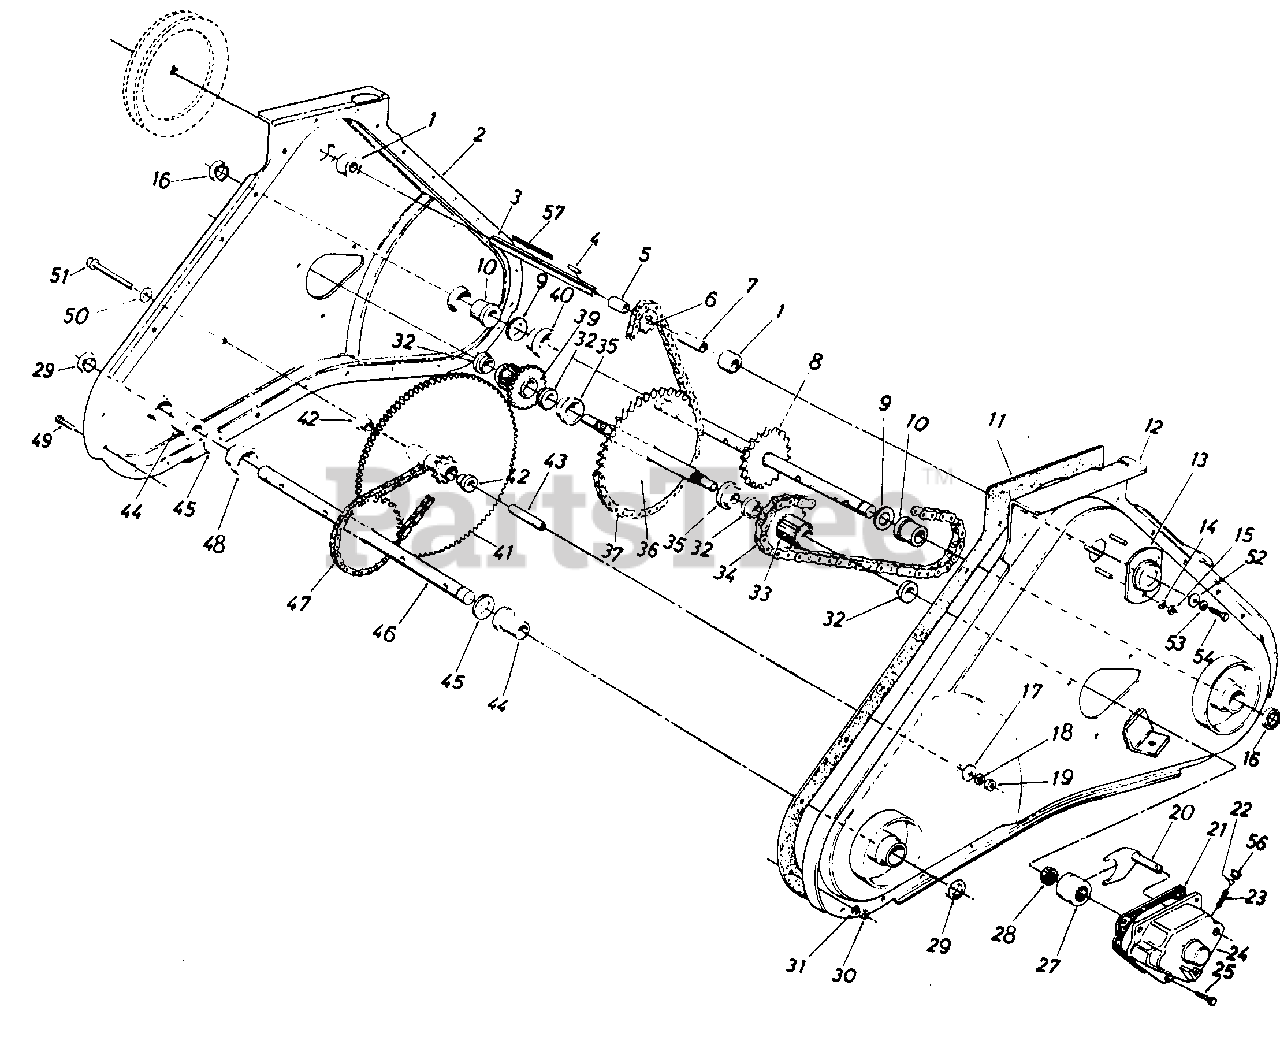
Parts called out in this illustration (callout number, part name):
1	Ball Bearing .62" I.D. x 1.38" O.D. x .44
2	Chain Case R.H. Half
3	Input Shaft .62" Dia.
4	Sq. Key 3/16" x 3/16" x .75" Lg.
5	Spacer .637" I.D. x .781" O.D. x.85" Lg.
6	Sprocket 9 Tooth x .62" Shaft
7	Spacer.637" I.D. x .781" O.D. x 1.44" Lg.
8	Tine Shaft Ass'y.
9	Fl-Wash. 1.28" I.D. x 1.62" O.D.
10	Flange Bearing 1.25" I.D.
11	Gasket Housing
12	Chain Case L.H. Half
13	Bearing Housing 1-3/8" O.D.
14	L-Wash. 1/4" I.D.*
15	Hex Nut 1/4-28 Thd.
16	Seal 1.25" I.D.
17	Belleville Wash.
18	L-Wash. 3/8" I.D.*
19	Hex Cent. L-Nut 3/8-24 Thd.
20	Shift Yoke Ass'y. L.H.
20	Shift Yoke Ass'y. R.H.
21	Gasket Shift Housing
22	Ball Detent .250 Dia.
23	Compression Spring
24	Shift Housing L.H.
24	Shift Housing R.H.
25	Hex Tap-Tite 5/16-18 x .75" Lg.
27	Clutch Dog
28	Clutch Dog Driver
29	Seal 1.0" I.D. x 1.38" O.D.
30	Hex Nut 1/4-28 Thd.*
31	L-Wash. 1/4" I.D.*
32	Flange Brg. 1.00" I.D.
33	Sprocket Brg. Sleeve Ass'y.
34	#50 Chain 5/8" Pitch x 50 0 Links Endless
35	Stepped Spacer 1.0" I.D. x 1.75" O.D.
36	Clutch Shaft Ass'y.
37	#420 Chain 1/2" Pitch x 58 Links Endless
39	Gear Beari ng Sleeve Ass'y.
40	Spacer 1.25" I.D. x 2.0" O.D. x .68" Lg.
41	Sprocket and Gear Ass'y.
42	Flange Brg. .628" I.D. x .753" O.D.
43	Hub Sleeve .38" I.D. x .625" O.D.
44	Flange Brg. 1.00" I.D. x 1.188" O.D.
45	Fl-Wash. 1.0" I.D. x 1.62 O.D.
46	Axle Shaft Ass'y.
47	#420 Chain 1/2" Pitch 46 0 Links Endless
48	Spacer 1.0" I.D. x 2.0" O.D.
49	Hex Bolt 1/4-28 x .62" Lg.
50	Belleville Wash.
51	Hex Bolt 3/8-24 x 2.75" Lg.
52	Fl-Wash. 5/16" I.D.
53	L-Wash. 5/16" I.D.
54	Hex L-Bolt 5/16-24 x .75" Lg.
56	Cap Plug .250" Dia.
57	Sq. Key 3/16" x 2.0" Lg.
